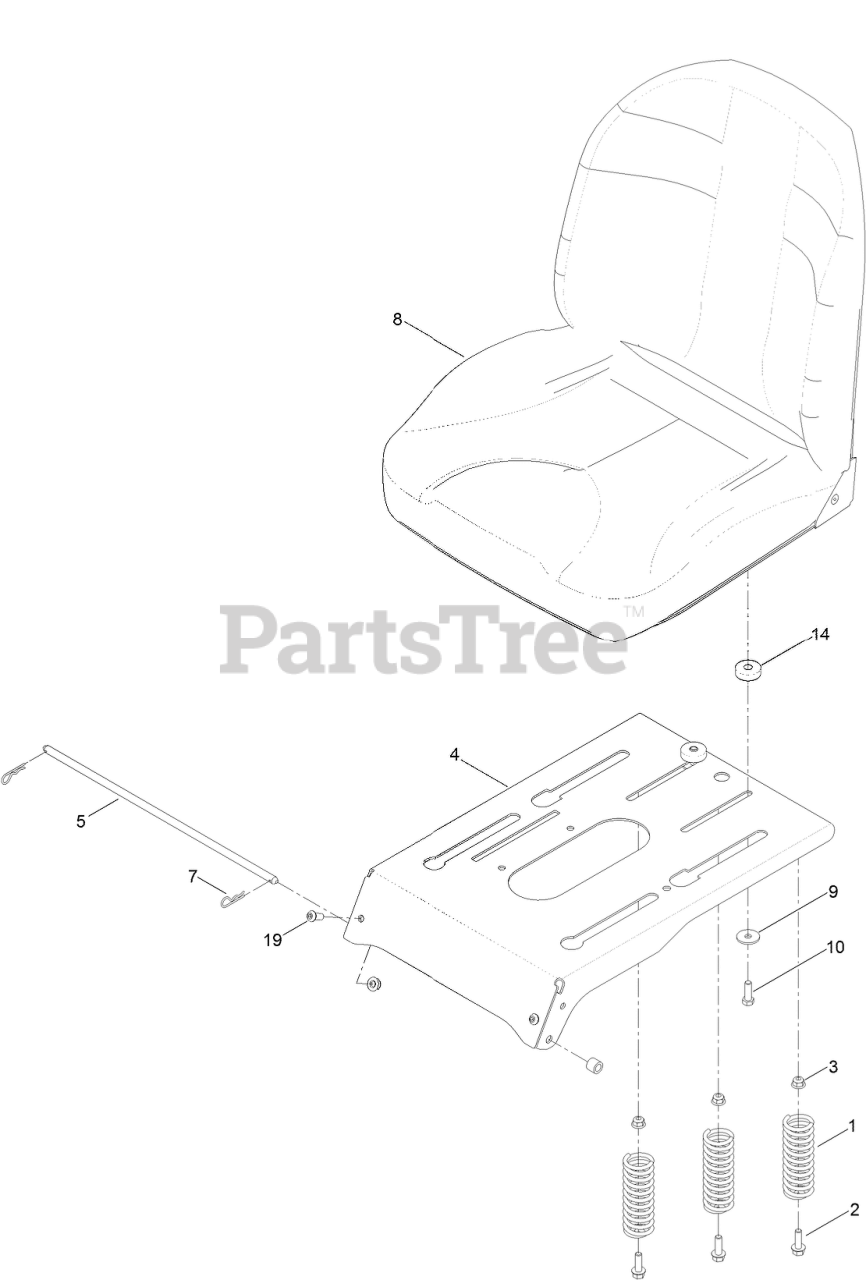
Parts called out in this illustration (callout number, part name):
1	SPRING-COMPRESSION
2	SCREW-HHF
3	NUT-HF, NI
4	PAN-SEAT, DELUXE
5	ROD-PIVOT, NARROW
7	PIN-COTTER
9	WASHER-PIVOT
10	SCREW-HH
14	BUSHING-SLIDE, SEAT
19	SCREW-HSBH
